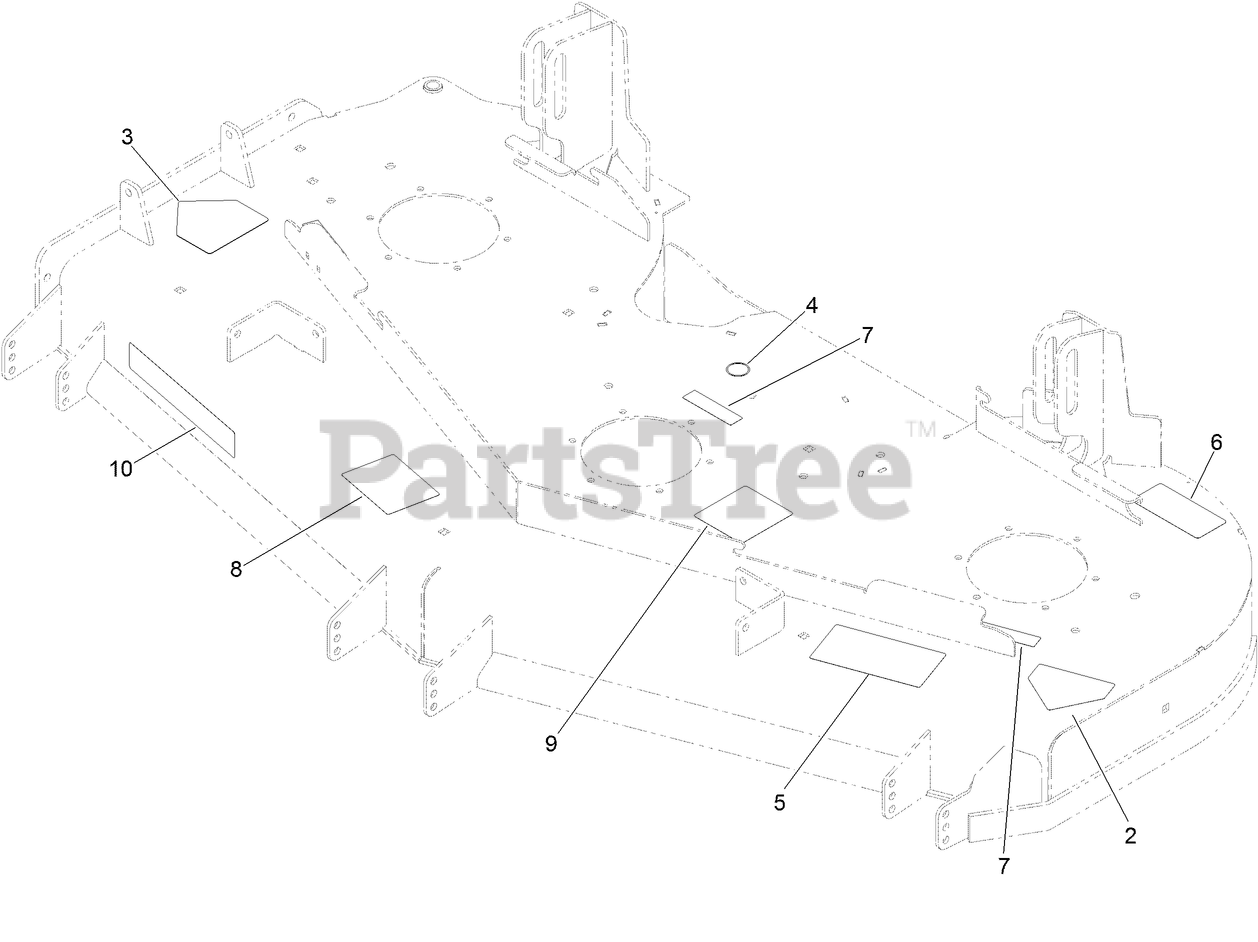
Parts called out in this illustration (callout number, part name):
2	DECAL-DANGER
3	DECAL-DANGER
4	DECAL-GREASE
5	DECAL-DANGER, THROWN OBJECT
6	DECAL-TORQUE
7	DECAL-COVER, MISSING
8	DECAL-SCALP, ANTI
9	DECAL-ROUTING, DECK BELT
